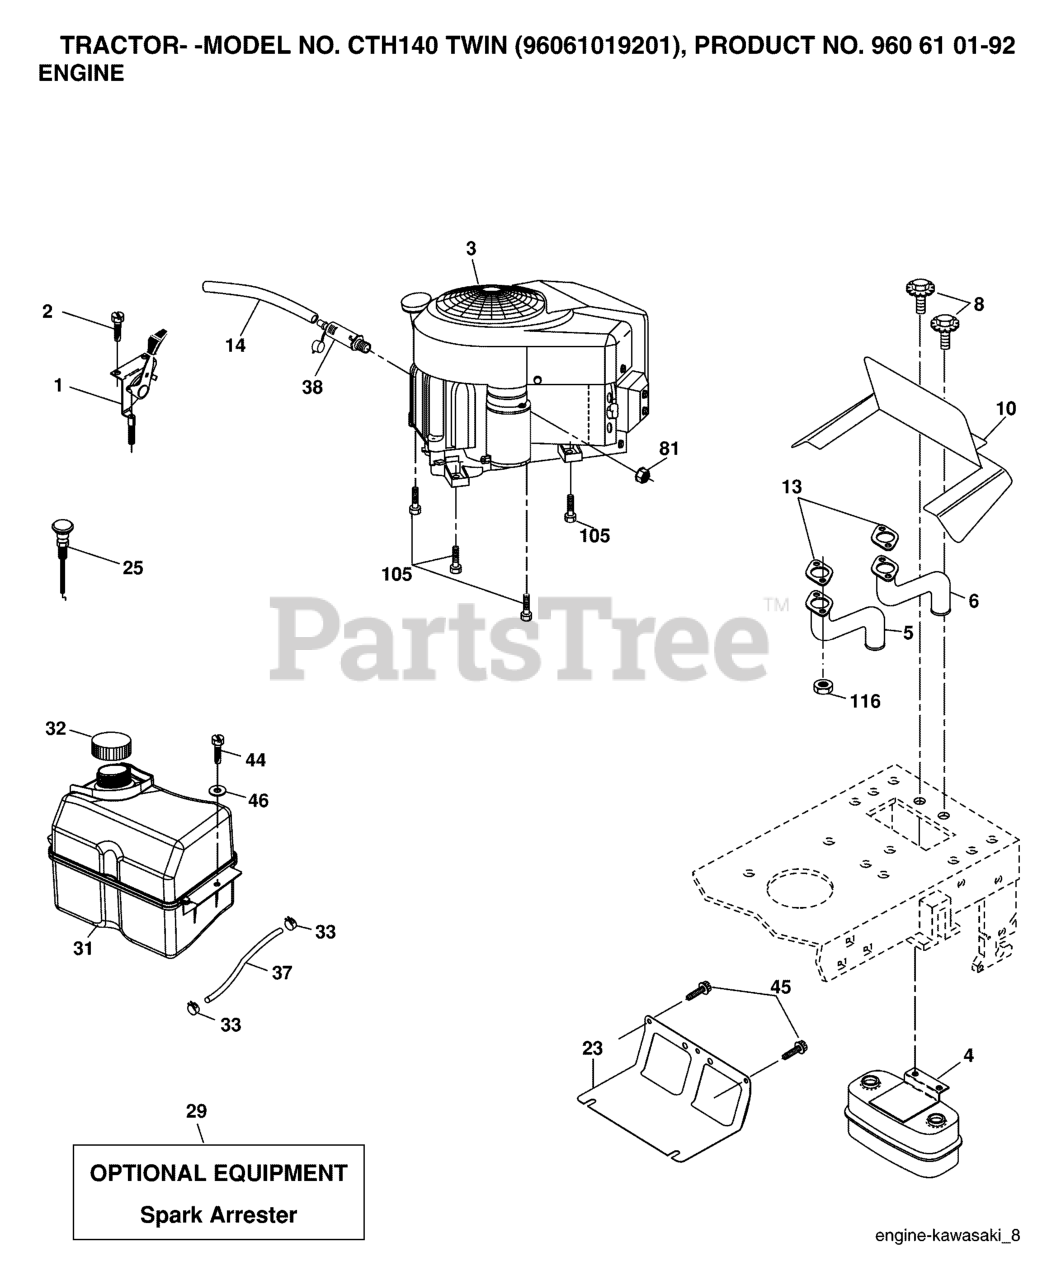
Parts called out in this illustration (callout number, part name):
1	CONTROL.THROTTLE.COBRA.BLACK
2	SCREW
4	MUFFLER.TWIN.CYL.LOW.TONE
5	EXHAUST TUBE LH KAWI
6	EXHAUST TUBE RH KAWI
8	BOLT.5/16-18UNCX3/4 W/SEMS.BLK
10	RP SHIELD HEAT MUFFLER
14	TUBE, DRAIN OIL ASM.
23	SHIELD.BROWNING.DBR.GUARD
25	CONTROL.CHOKE.ERGO.PUSH-IN.BLA
29	KIT.SPARK ARRESTOR 794945 B&S
31	RP TANK FUEL FRT 1.5 GAL
32	FUEL CAP
33	HOSE CLAMP
37	LINE.FUEL.20
44	SCREW HEXWSHR 1/4-20X3/4
45	SCREW, 3/8-16X3/4
81	NUT
105	SCREW 3/8-16X1
116	NUT.HEX.FLANGE.TOPLOCK
